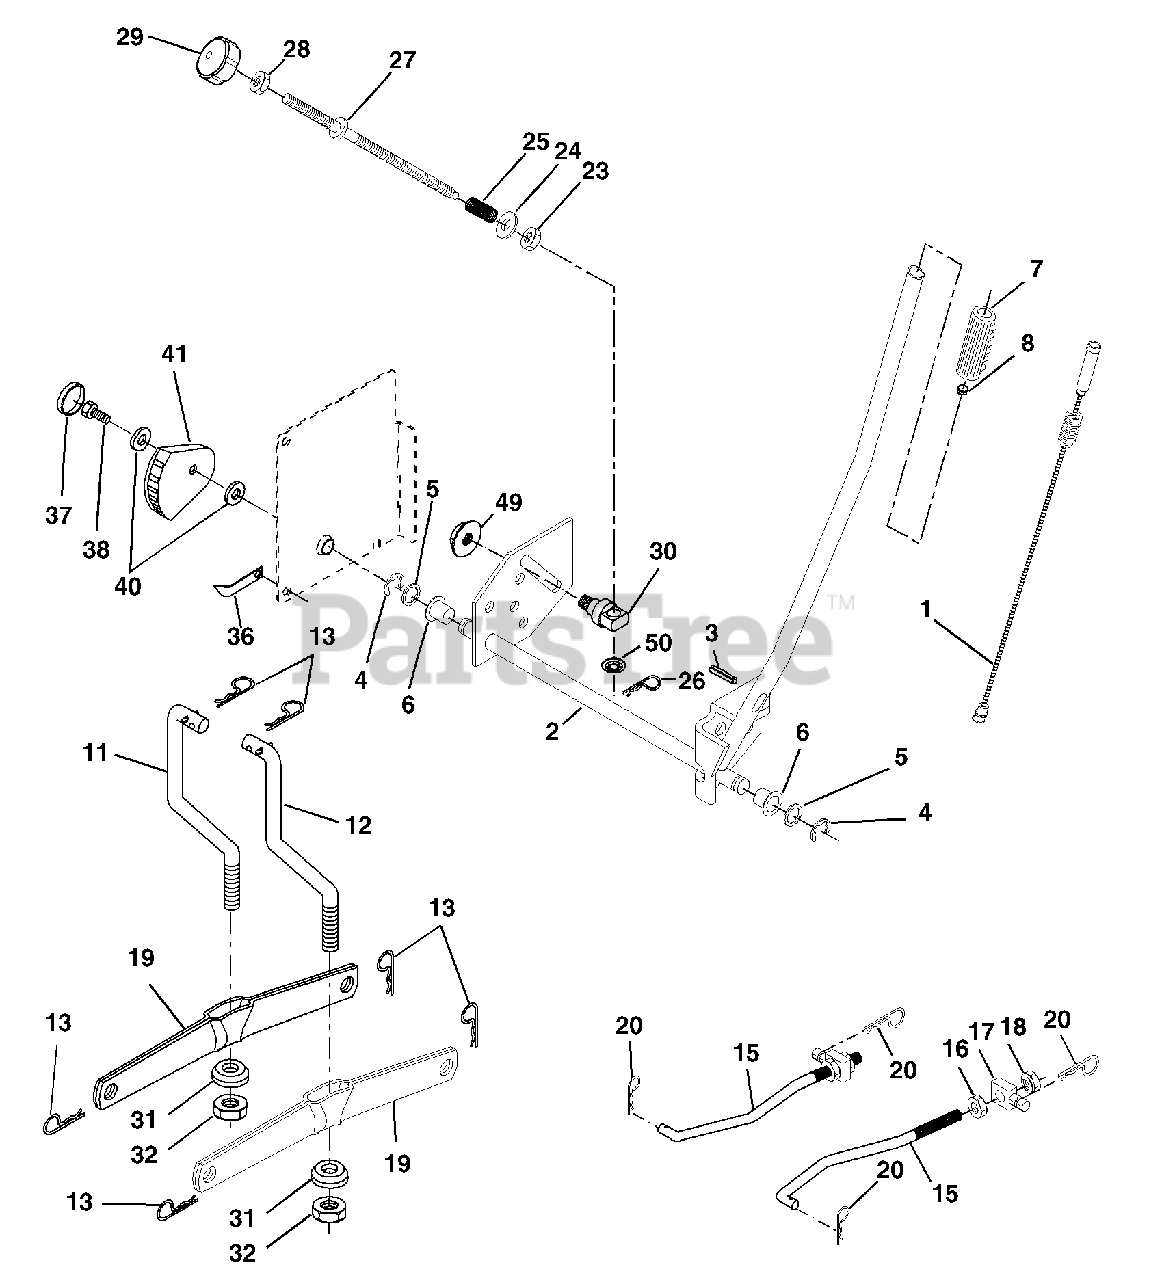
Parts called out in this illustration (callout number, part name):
1	Wire Asm Inner/Sprg W/plunger
2	Shaft Asm Lift RH w/Inf
3	Pin Groove
4	E Ring #5133-62
5	Washer 21/32 X 1 X 21 Ga
6	Bearing Nylon Blk 629 Id
7	Grip Handle
8	Button Plunger
11	Link Lift LH
12	Link Lift RH
13	Retainer Spring
15	Link Suspension Front
16	Nut Jam Hex 1/2-13 Unc
17	Trunnion Front Susp.
18	Nut Lock w/Wsh 1/2-13unc
19	Arm Asm Suspension Mower
20	Retainer Spring
23	Nut Special
24	Washer 13/32 X 5/8 X 16 Ga
25	Spring
26	Retainer Clip
27	Rod Adj Lift
28	Nut Hex Jam 3/8-16 Unc
29	Knob Inf 3/8-16 Unc Blk W/sym
30	Trunnion Infin Height
31	Lift Pivot Bearing
32	Nut Crownlock 3/8-24
36	Pointer Height Indicator
37	Plug Hole Blk 1.485/1.515 Dia.
38	Screw 5/16-18 x 1
40	Washer 11/32 x 1-1/2 10 Ga.
41	Indicator Height STLT
49	Nut Hex Flange Lock
50	Nut PUsh Phos & Oil
